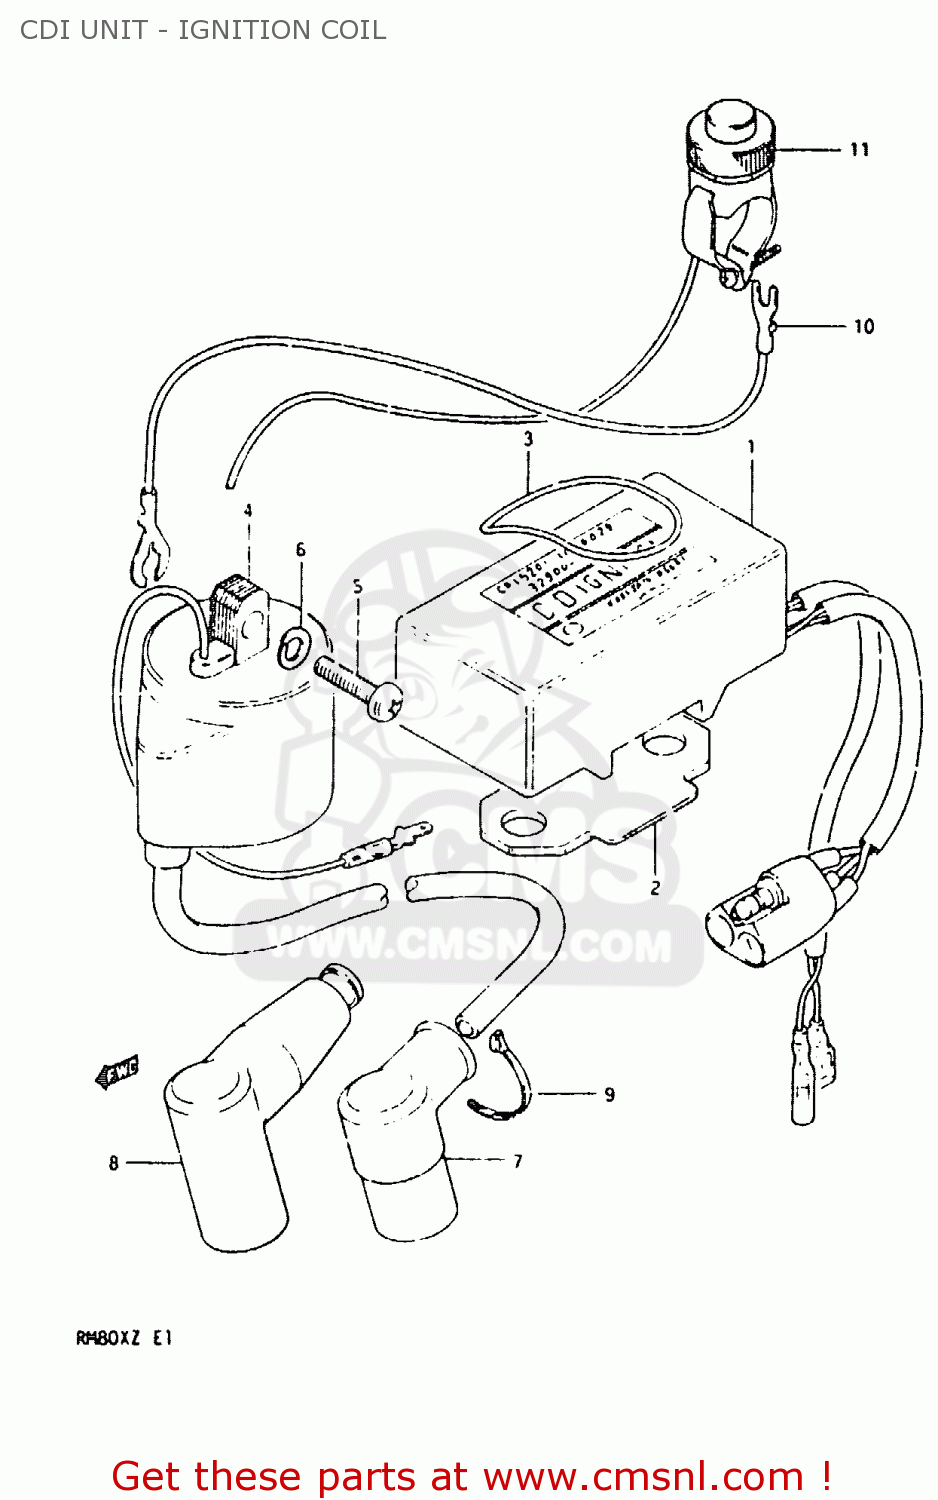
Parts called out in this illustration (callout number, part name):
1	CDI UNIT
2	PROTECTOR,CDI UNIT
3	O-RING
4	COIL ASSEMBLY,IGNITION
5	SCREW
6	LOCK WASHER
7	CAP,SPARK PLUG
8	CAP, SPARK PLUG
9	CLAMP
10	WIRE,ENGINE STOP EARTH
11	SWITCH ASSEMBLY
